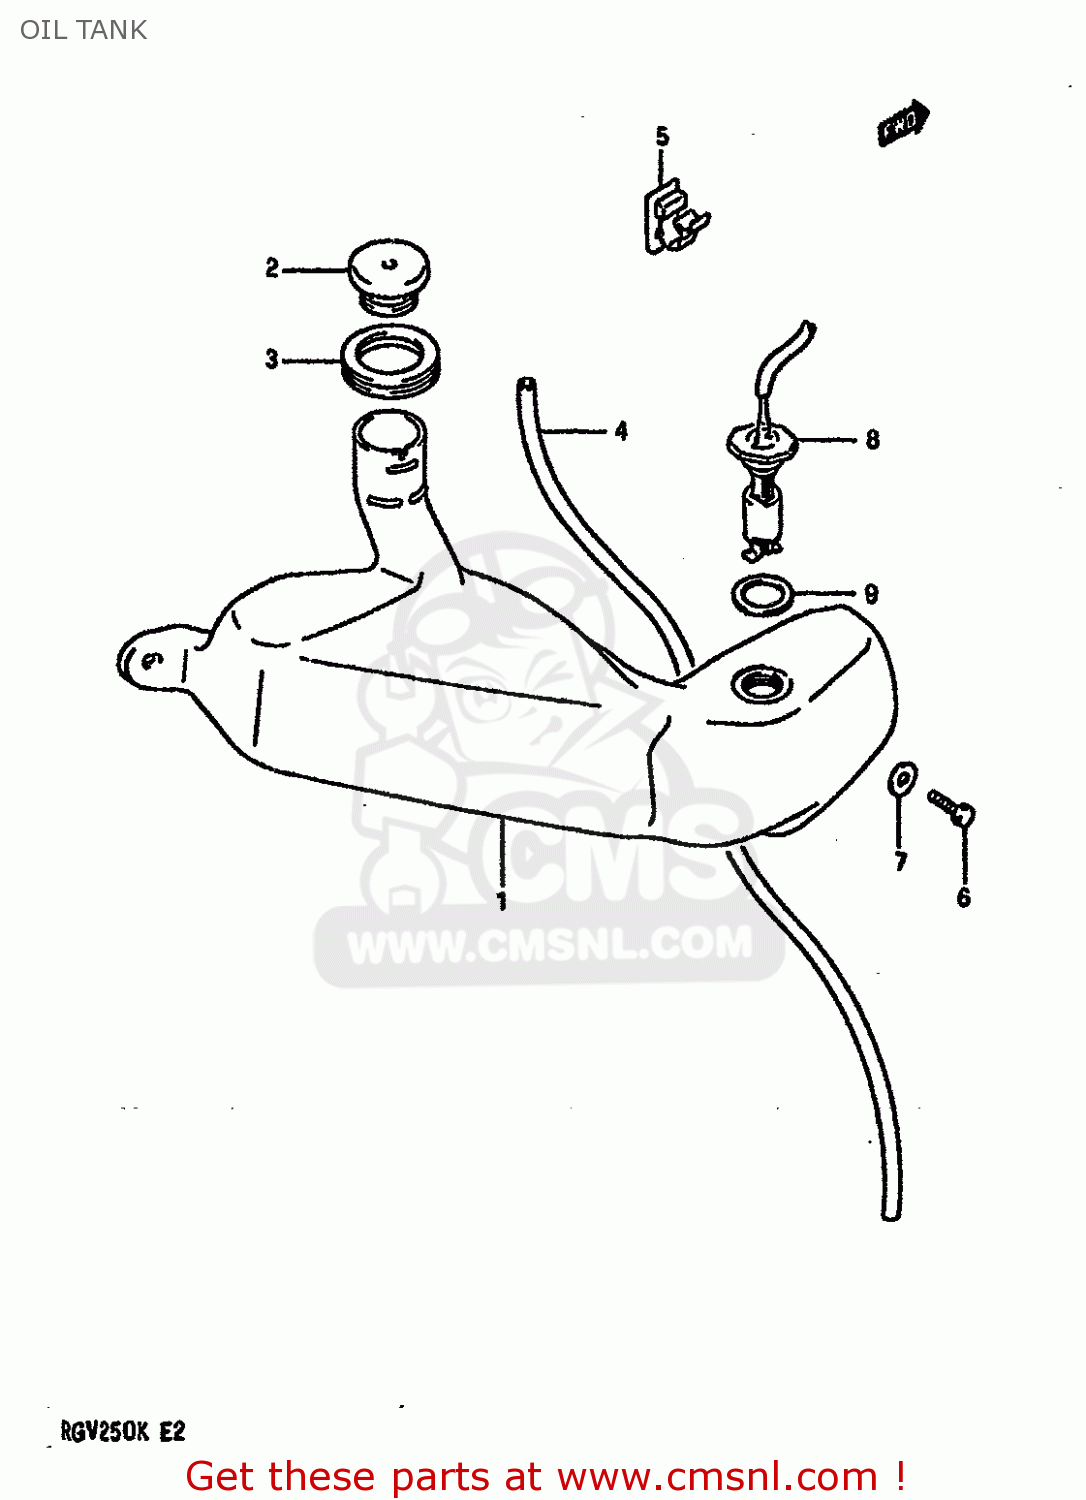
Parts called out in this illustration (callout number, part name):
1	TANK,OIL
2	CAP,OIL TANK
3	RUBBER,OIL TANK INLET
4	HOSE
5	CLAMP
6	BOLT(6X20)
7	WASHER(6.5X18X1)
8	SWITCH ASSY,OIL LEVEL
9	GASKET (NAS)
